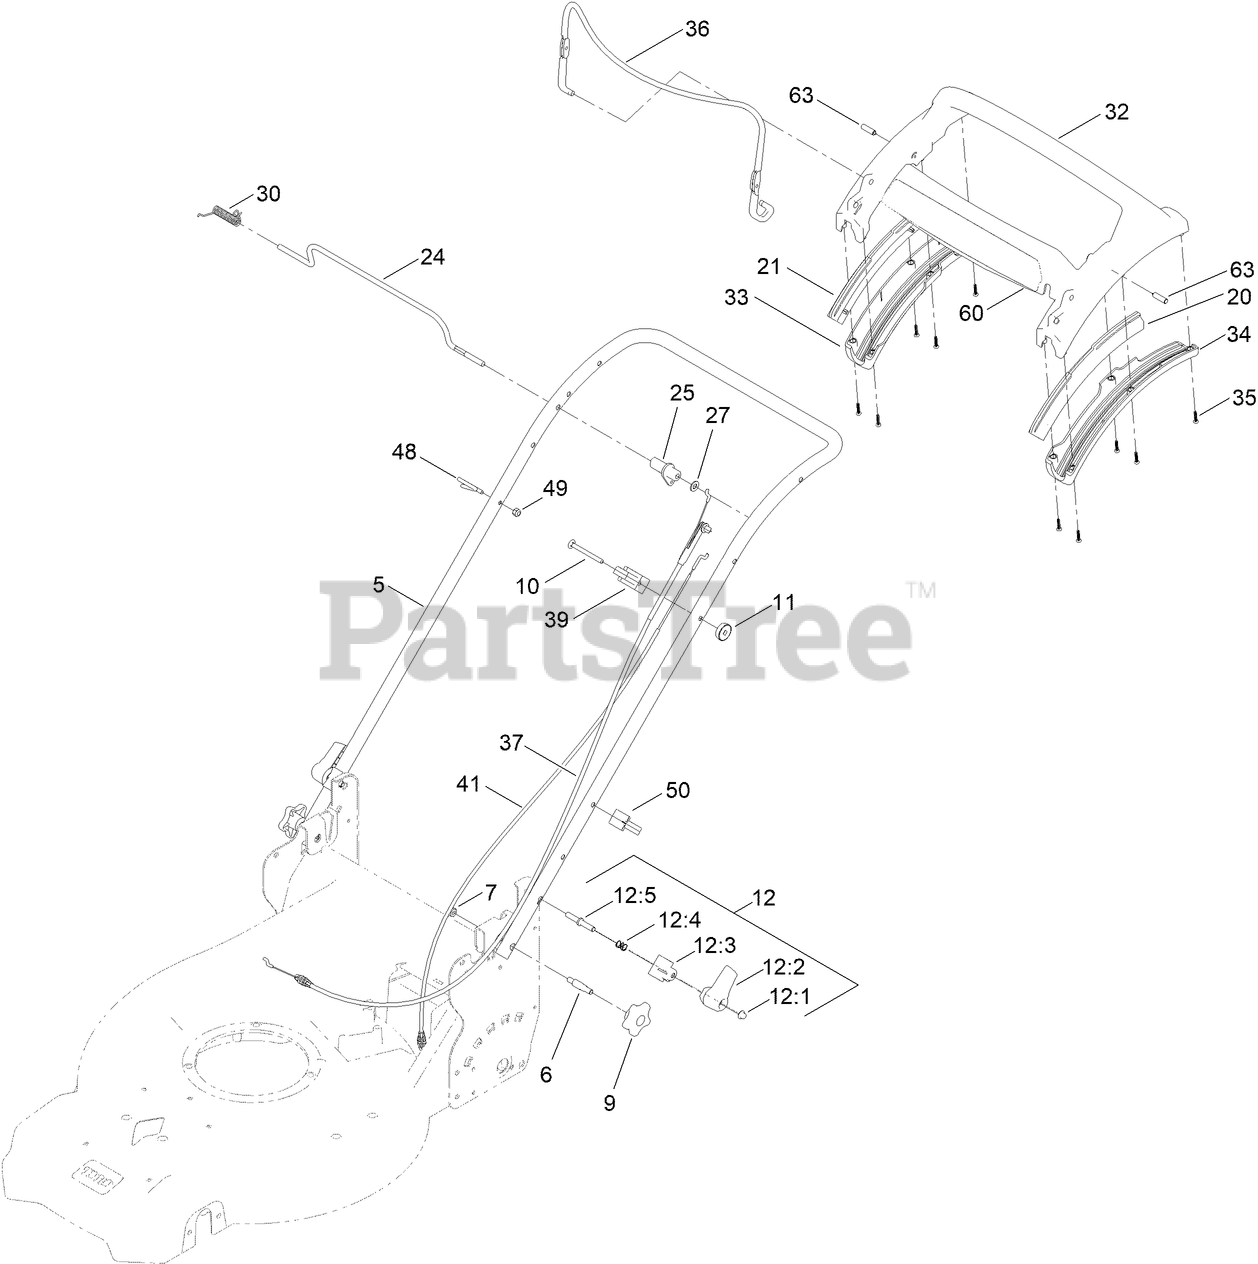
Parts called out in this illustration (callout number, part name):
5	HANDLE-CURVED
6	BOLT-SHOULDER, HANDLE
7	NUT-LOCK, NI
9	KNOB-HANDLE
10	SCREW-CARR
11	WASHER-CURVED
12	QUICK RELEASE ASM
12:1	NUT-PUSH
12:2	LEVER-RELEASE
12:3	ANCHOR-SPRING
12:4	SPRING-COMPRESSION
12:5	ROD-RELEASE
20	GUIDE-CURVED, LH (RWD)
21	GUIDE-CURVED, RH (RWD)
24	ROD-CONTROL, TRACTION
25	LEVER-TRACTION, RWD
27	WASHER-PLAIN
30	SPRING-TORSION
32	HANDLE-PERSONAL PACE, CURVED
33	BOTTOM-HANDLE, RH
34	BOTTOM-HANDLE, LH
35	SCREW-PPH
36	BAIL-BRAKE
37	CABLE-BRAKE, PP BS
39	ANCHOR-CABLE, RWD
41	CABLE-TRACTION, RWD (PP)
48	GUIDE-ROPE
49	NUT-HEX
50	GUIDE-CABLE
60	DECAL-HANDLE, PP
63	PIN-HANDLE, PP
